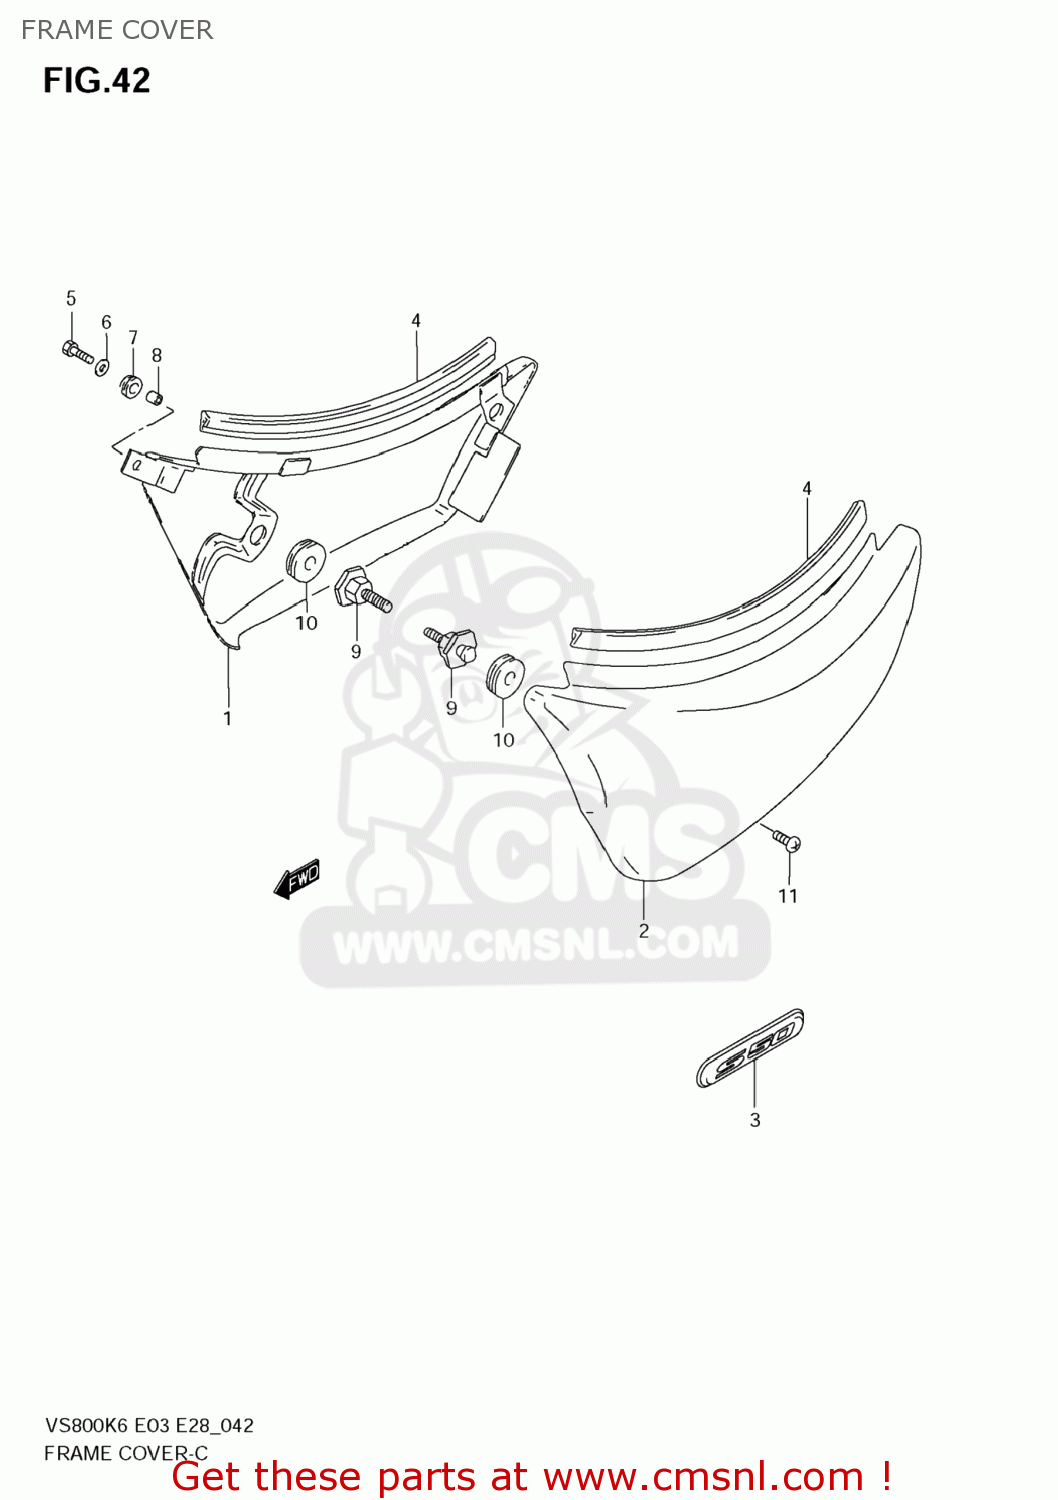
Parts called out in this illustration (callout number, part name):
1	COVER ASSY,FRAME,R(SILVER)
2	COVER ASSY,FRAME,L(SILVER)
3	EMBLEM,S50
4	MOLDING
5	BOLT
6	WASHER(6.5X18X1.6)
7	CUSHION
8	SPACER(6.1X8X5.2)
9	BOSS,FRAME COVER
10	CUSHION
11	SCREW
